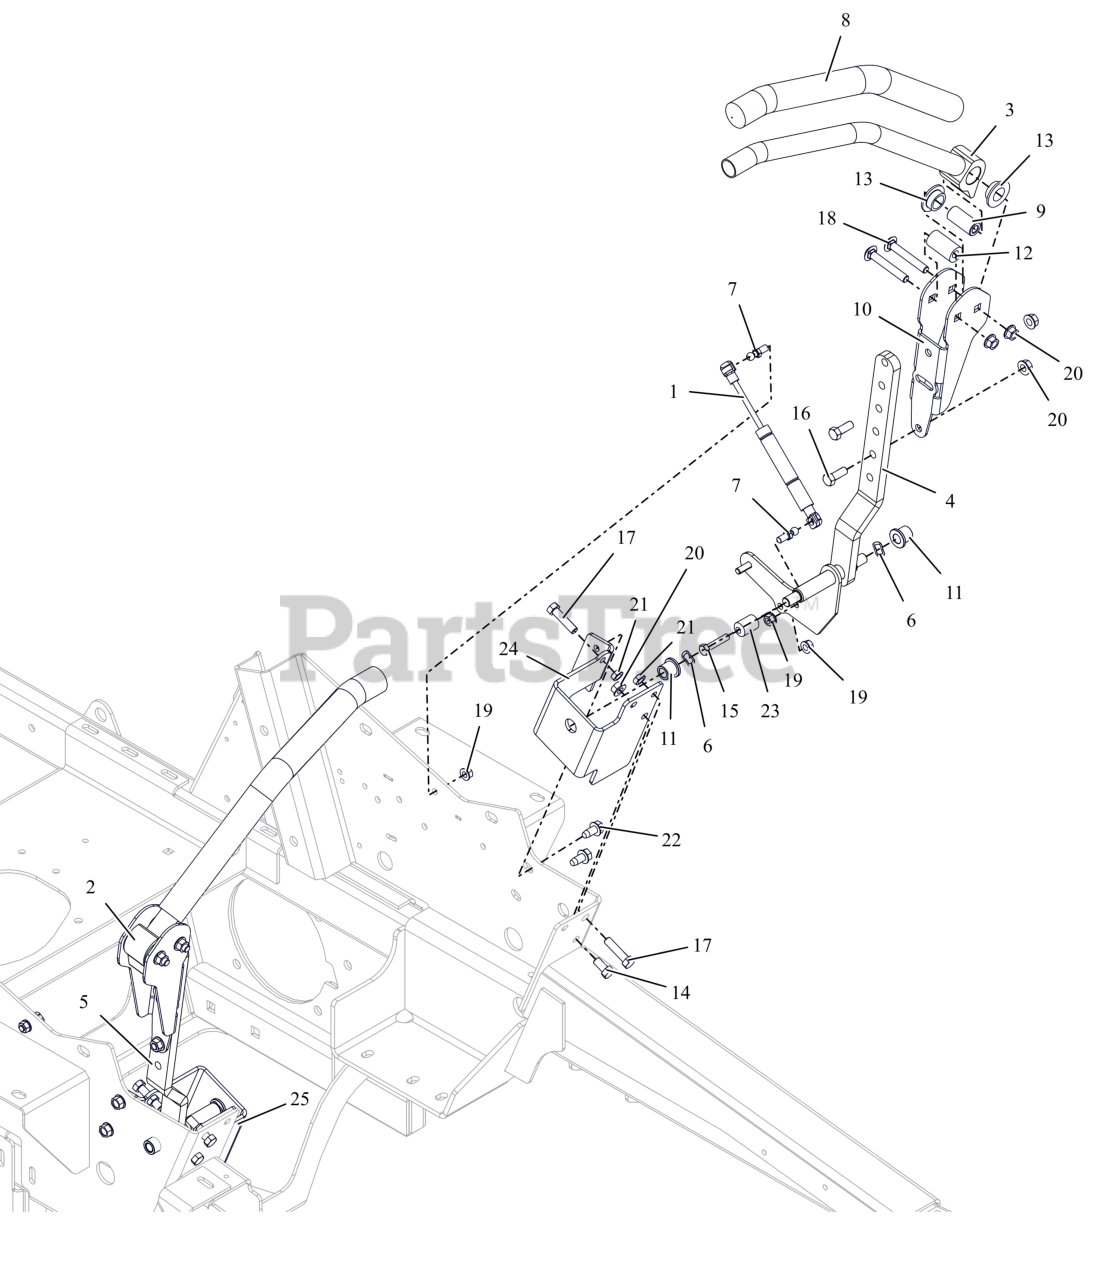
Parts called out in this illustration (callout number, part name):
1	DAMPER, CONTROL
2	WLDMT, CONTROL HANDLE (RED)
3	WLDMT, CONTROL HANDLE (RED)
4	WLDMT, LH LOWER CONTROL ARM (RED)
5	WLDMT, RH LOWER CONTROL ARM (RED)
6	WAVE WASHER .531X.781X.125FH
7	STUD- BALL
8	GRIP, HANDLEBAR
9	SPACER, STEERING ARM
10	BRKT, ADJ UPPER CONTROL ARM (RED)
11	BHSG-FLG .500X.750X.750X.125
12	BSHG, ECCENTRIC.406X.875X1.625
13	BSHG-FLG .762X1.48X.44 NYL
14	BLT,HEX .38-16X.75 G5 ZCC
15	BLT, HEX .31-18X1.50 G5 ZCC
16	BLT,HEX .38-16X1.00 G5 ZCC
17	BLT, HEX 0.375-16X1.5FULL G5 ZCC
18	BLT, RHSSN.38-16X2.50 G5 ZCC
19	NUT,LK-CTR-FLG .31-18 GF ZCC
20	NUT-LK-CTR-FLG .375-16 GF ZCC
21	NUT-JAM .375-16 G2 ZCC
22	SCR,TAP .375-16X.75 HWH TR ZCC
23	ECCENTRIC
24	BRKT, CONTROL ARM - LEFT (RED)
25	BRKT, CONTROL ARM - RIGHT (RED)
